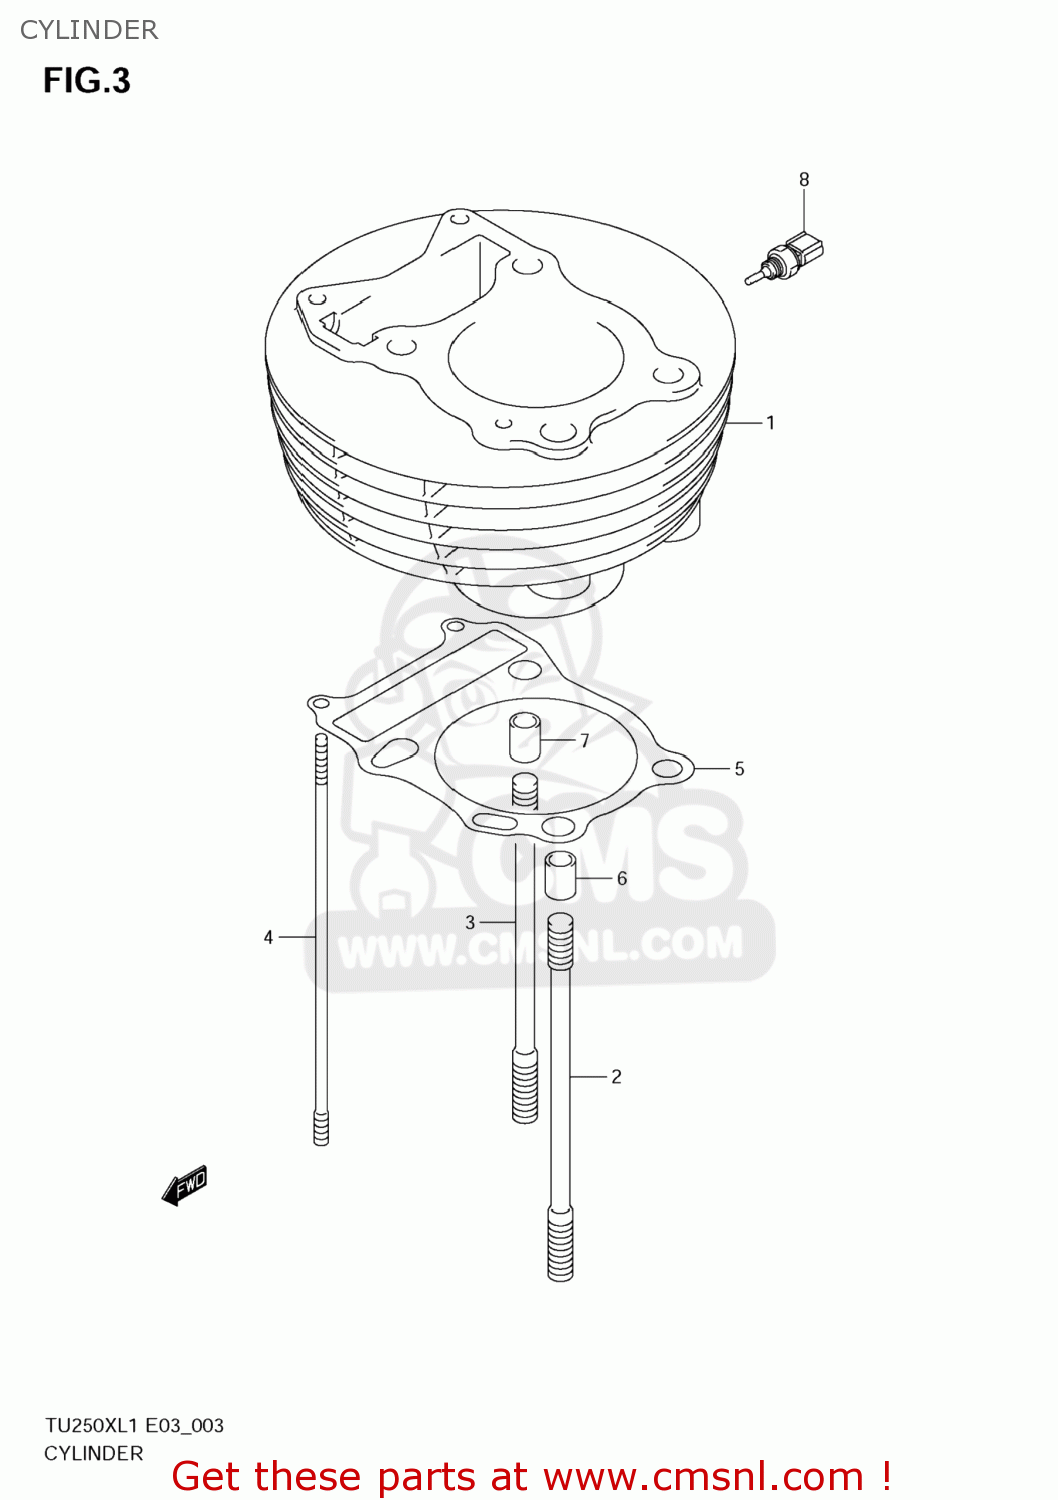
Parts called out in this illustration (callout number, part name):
1	CYLINDER
2	BOLT,STUD
3	BOLT,STUD
4	BOLT,STUD
5	GASKET,CYLINDER (NAS)
6	PIN
7	PIN
8	SENSOR,ENGINE TEMP
